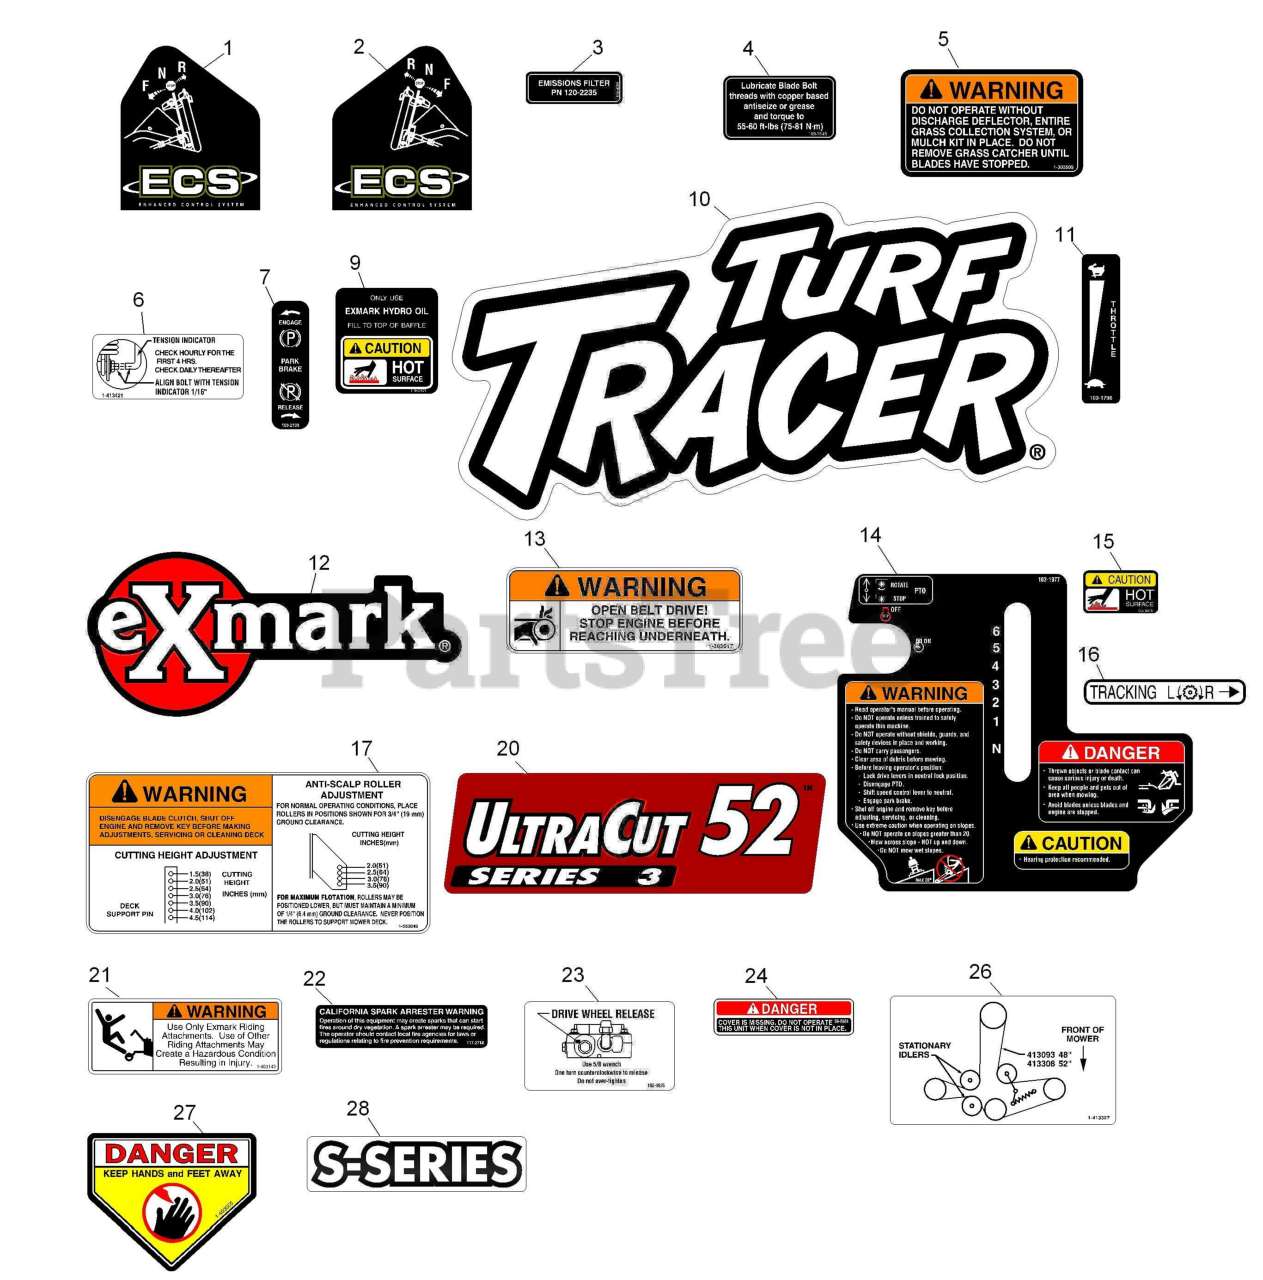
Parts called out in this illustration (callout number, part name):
1	DECAL,LH ECS INSTRUCTION
2	DECAL,RH ECS INSTRUCTION
3	DECAL-FILTER, EMISSIONS
4	DECAL,BOLT TORQUE
5	DECAL-WARNING, DISCHARGE
6	DECAL,INDICATOR
7	DECAL-BRAKE, PARK
9	DECAL-HYDRAULIC TANK
10	DECAL,TTH MODEL
11	DECAL,THROTTLE ONLY
12	DECAL,EXMARK LOGO
13	DECAL,BELT DRIVE
14	DECAL,ECS CONSOLE
15	DECAL-CAUTION
16	DECAL,TRACKING ADJUST
17	DECAL,ANTI SCALP
20	DECAL-ULTRACUT 52 SERIES
21	DECAL,SULKY WARNING
22	DECAL-ARRESTER, SPARK
23	DECAL,DRIVE RELEASE
24	DECAL-COVER, MISSING
26	DECAL,BELT ROUTING
27	DECAL-DANGER
28	DECAL-S-SERIES
